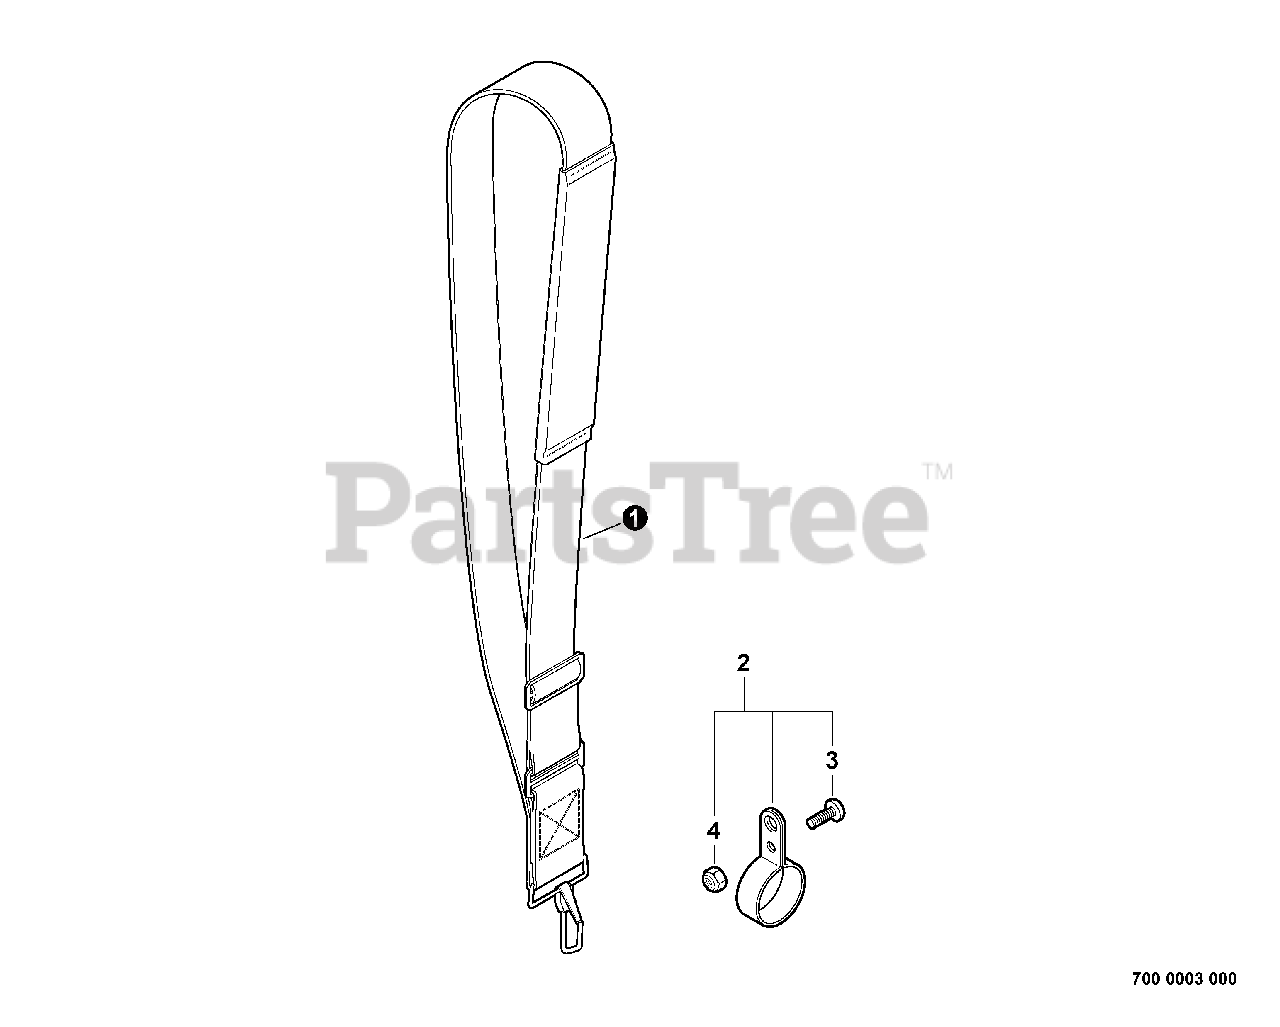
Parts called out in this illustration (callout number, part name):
1	STRAP ASSY, SHOULDER
2	HANGER KIT
3	SCREW
4	NUT, LOCK 10-24 UNC
